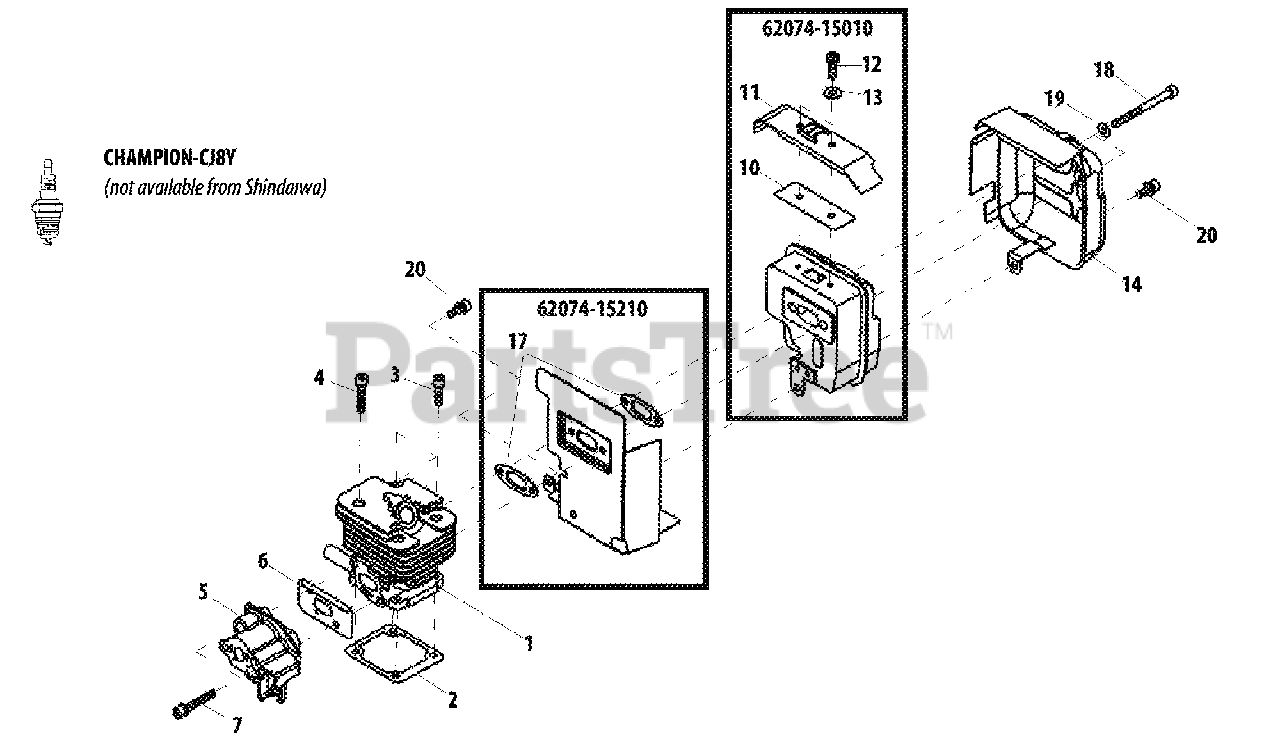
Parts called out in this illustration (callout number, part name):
1	CYLINDER
2	GASKET, CYLINDER
3	SCREW - 5X16
4	SCREW - 5X30
5	INSULATOR
6	GASKET
7	SCREW - 5X30
10	SCREEN, SPARK ARRESTOR
11	TAIL PLATE
12	SCREW - 4X6
13	WASHER - 4
14	COVER, MUFFLER
17	GASKET
18	SCREW - 5X60
19	WASHER - 5
20	SCREW - 5X12
6207415010	MUFFLER ASSY
6207415210	GASKET
